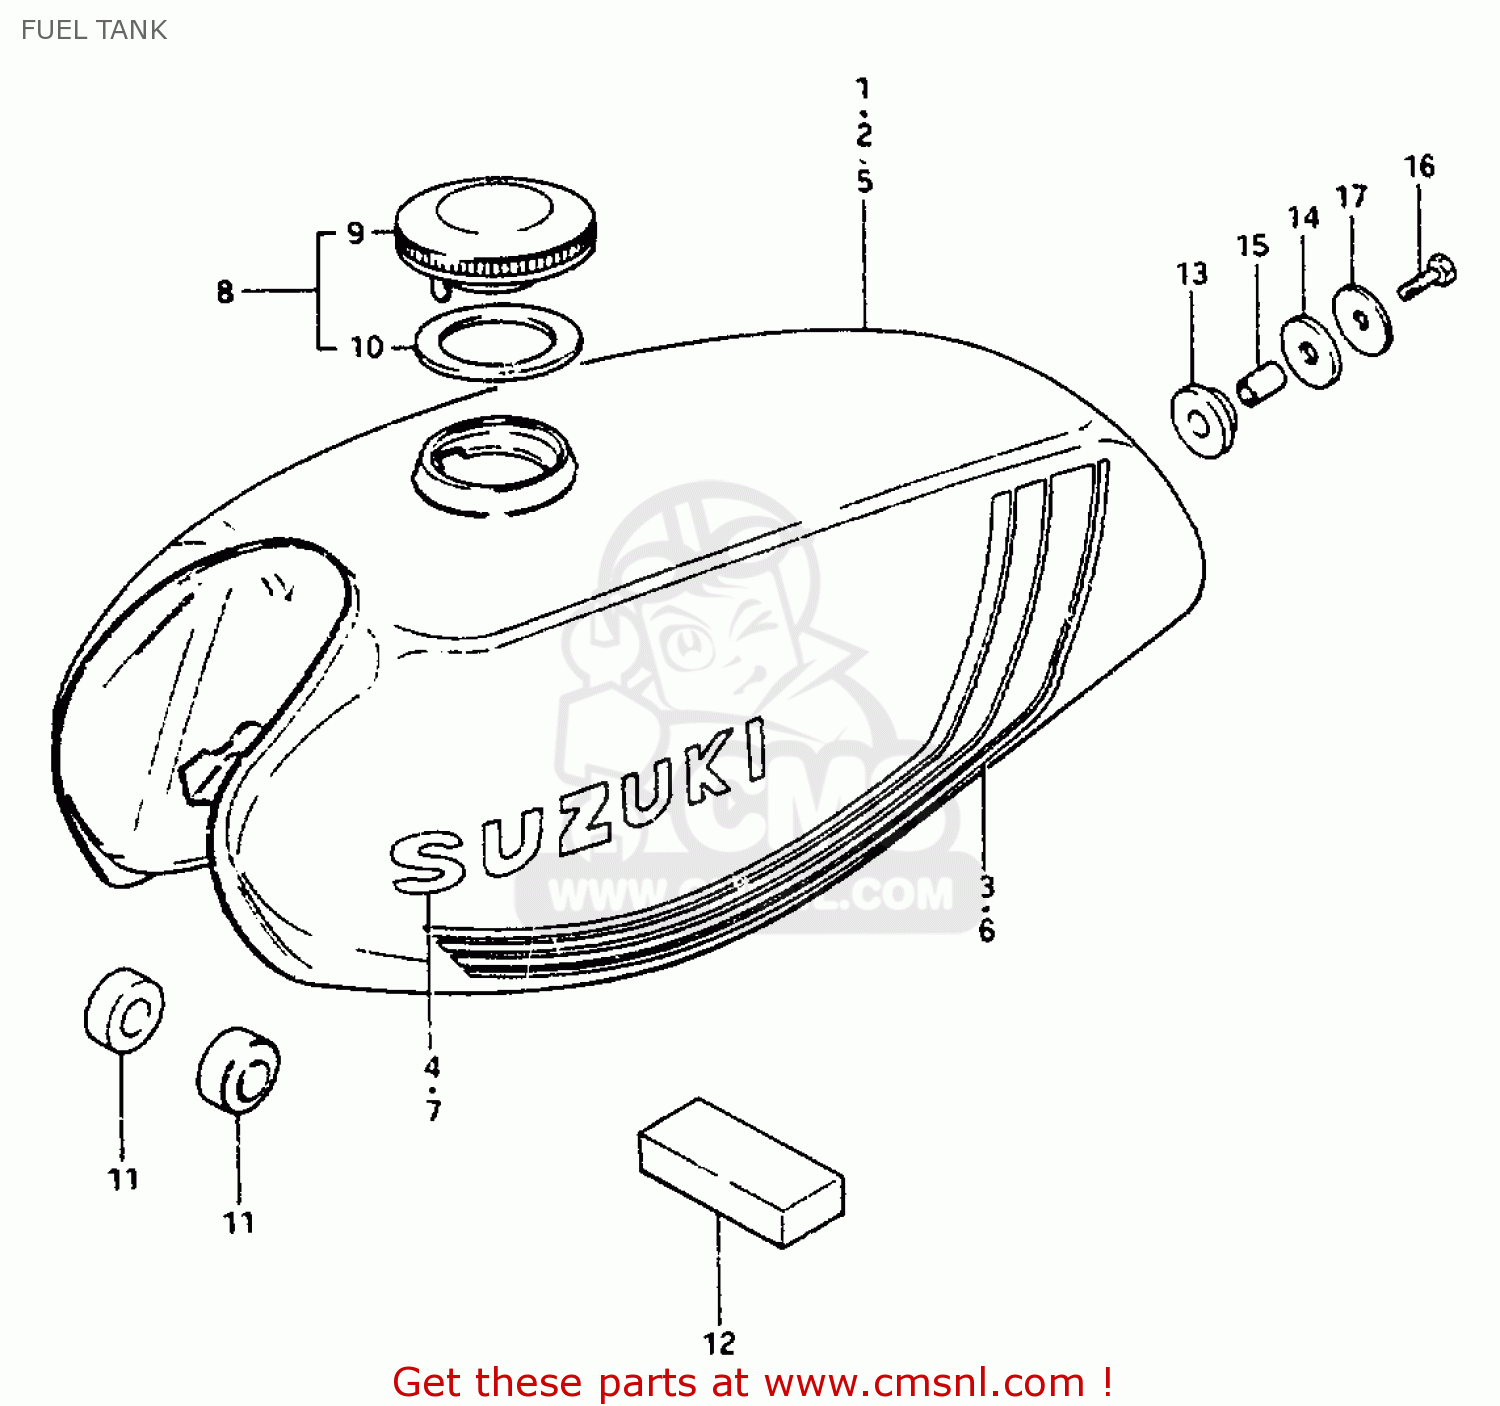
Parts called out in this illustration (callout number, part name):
1	TANK, FUEL (BLUE)
2	TANK, FUEL (RED)
3	TAPE SET
4	EMBLEM
5	TANK, FUEL (WHITE)
6	TAPE SET
7	EMBLEM(BLACK)
8	CAP ASSY,FUEL TANK FILLER
9	CAP,FUEL TANK
10	GASKET (NAS)
11	CUSHION
12	CUSHION
13	CUSHION
14	CUSHION
15	SPACER(8.5X12X19)
16	BOLT (8X30)
17	WASHER (8.5X29X1.6)
